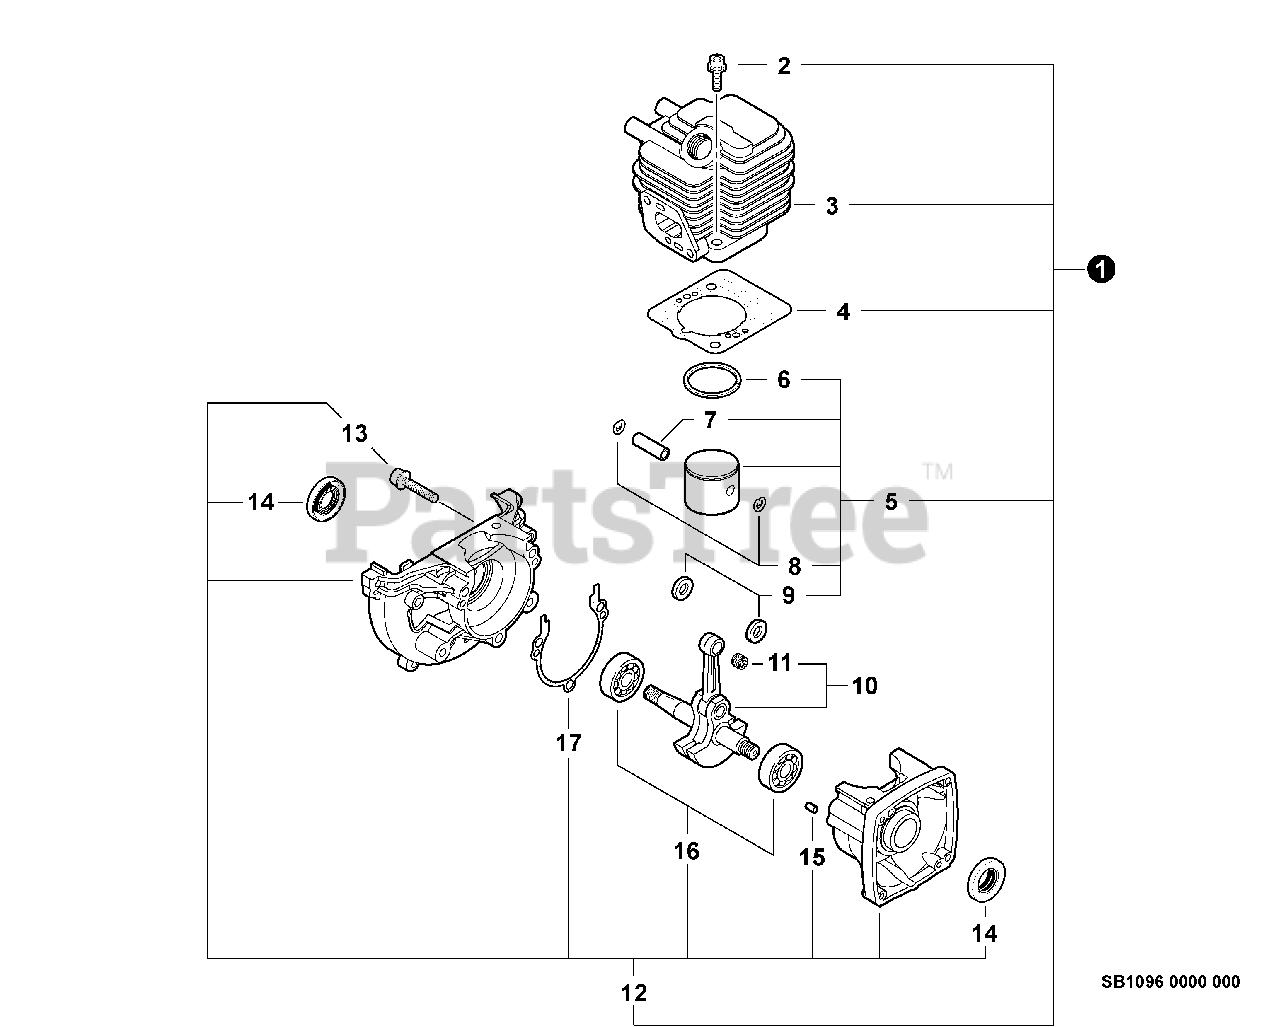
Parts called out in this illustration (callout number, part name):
1	SHORT BLOCK -- SB1096
2	SCREW - 5X22
3	CYLINDER
4	GASKET, CYLINDER
5	PISTON KIT
6	RING, PISTON
7	PIN, PISTON
8	RING, RETAINING
9	SPACER, PISTON
10	CRANKSHAFT ASSY
11	BEARING, NEEDLE - 8
12	CRANKCASE KIT
13	SCREW - 5X28
14	SEAL, OIL
15	PIN - LOCATING
16	BEARING, BALL - 6201
17	GASKET, CRANKCASE
